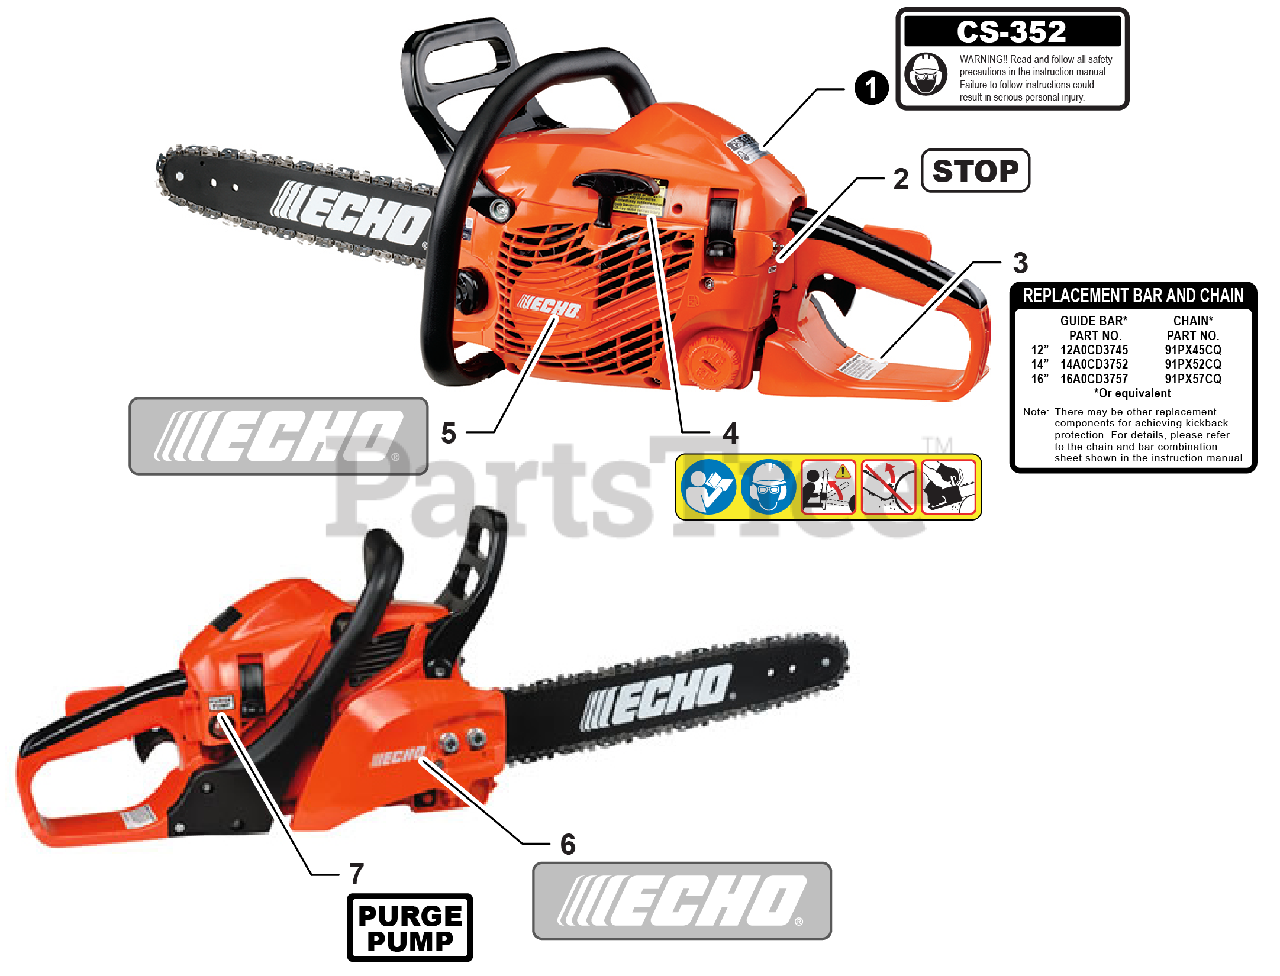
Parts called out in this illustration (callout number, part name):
1	LABEL, CS-352
2	LABEL, STOP
3	LABEL, BAR & CHAIN
4	LABEL, CAUTION
5	LABEL, ECHO
6	LABEL, ECHO
7	LABEL, PURGE PUMP
